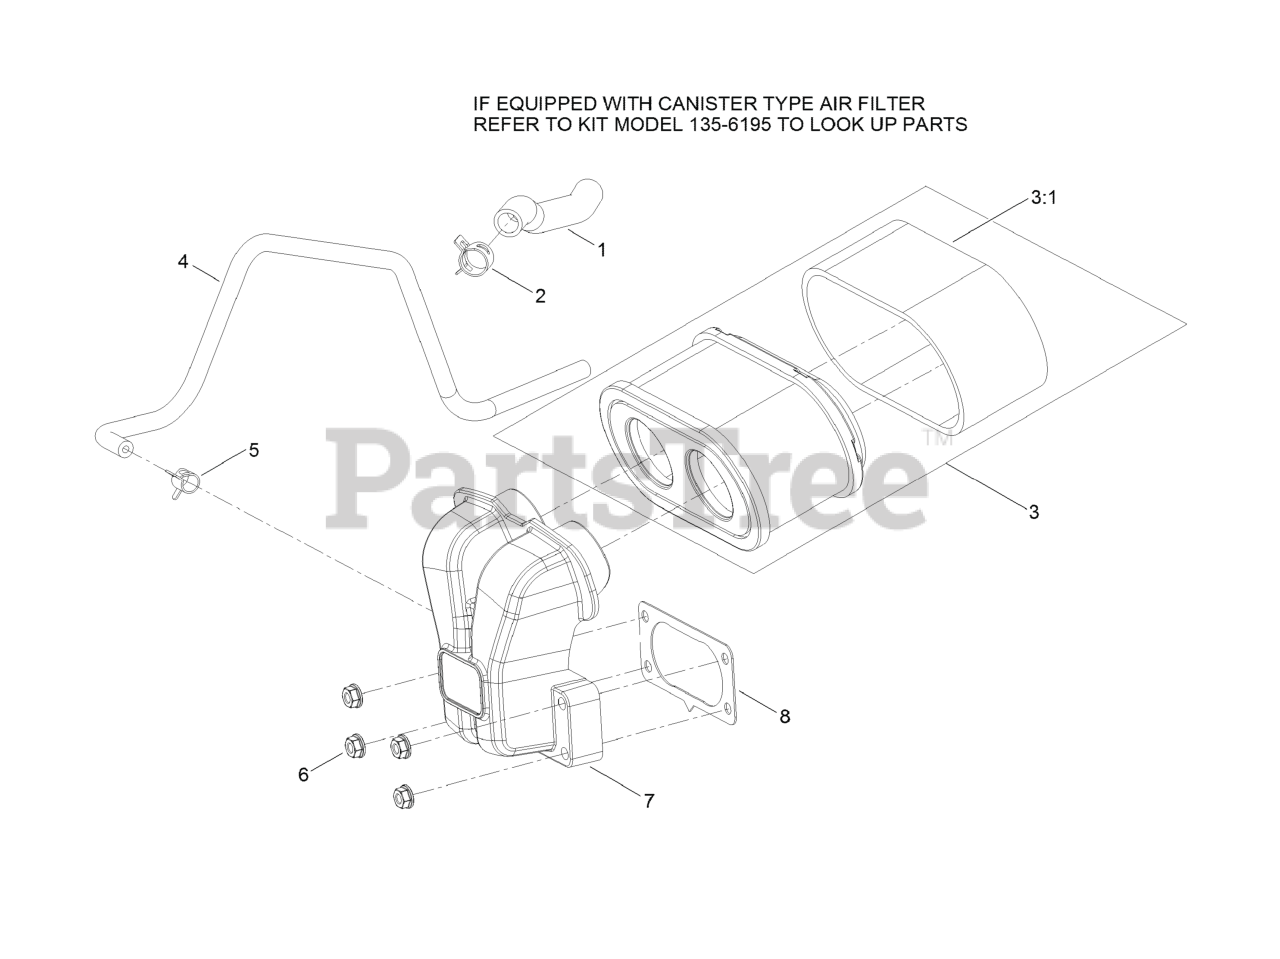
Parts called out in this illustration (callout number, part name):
1	TUBE-BREATHER
2	CLAMP-HOSE
3	AIR FILTER KIT
3:1	PREFILTER
4	HOSE-FUEL
5	CLAMP-HOSE
6	NUT-FLANGE
7	MANIFOLD-FILTER, AIR
8	GASKET-CARBURETOR
